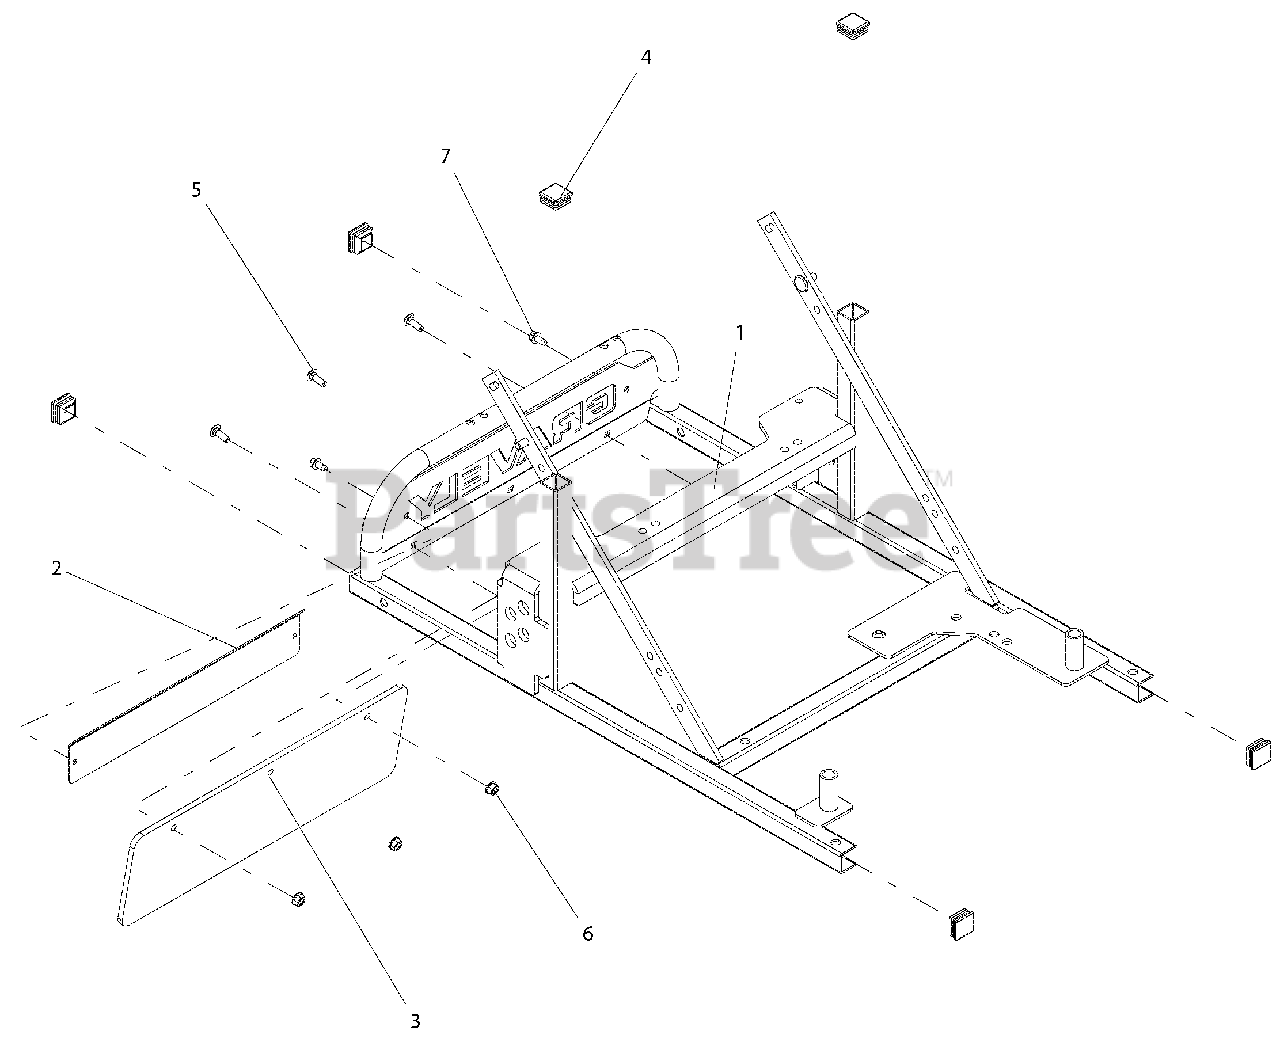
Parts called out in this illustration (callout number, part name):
1	WLDMT, HIGH WHL MWR FRAME
2	BACKER, GRAVELY
3	GUARD, RUBBER DEBRIS
4	CAP PLUG FOR 1" TUBE 14GA
5	BLT-RDHDSQNK .25-20X.75 G5 YWZC
6	NUT, LK-TOP-FLG .25-20 YWZC
7	SCR-TAP .25-20X.50 HWH TR YWZ
